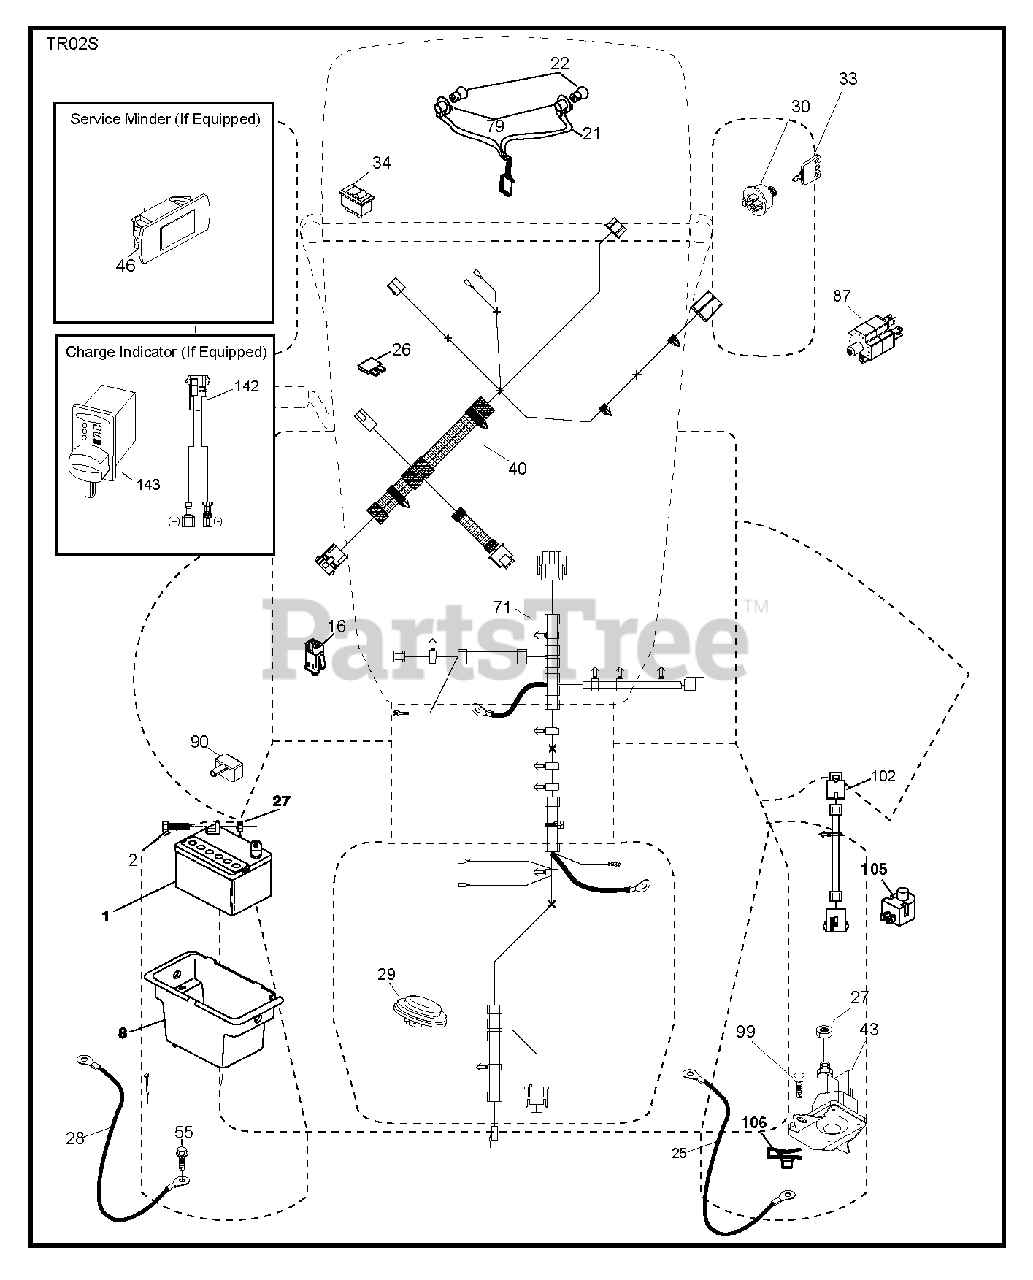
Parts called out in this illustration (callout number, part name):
1	Battery, Dry 30 Amp
2	BOLT.HEX.1/4.X.3/4.DICHROMATE
8	BOX.BATTERY.MNT.REAR.L
16	SWITCH INTERLOOK PUSH-IN
21	HARNESS.LIGHT W/4152J BULBS
25	CABLE.BATT.RED.8GA.17
26	FUSE 20AMP
27	NUT
28	CABLE.GROUND.REAR.BATTERY.8G
29	SWITCH.SEAT.DELTA.OPC.
30	SWITCH.IGN.DELTA.W.LGH.ROS
33	KEY.CHAIN.BLISTER.PACK.GEN.INT
40	HARNESS.DASH.RRBATT.CC.CHG
43	SOLENOID.STARTER.BRASS.PLUNGER
55	SCREW 5/16"
71	HARNESS.CHASSIS.RRBATT.RDYSTRT
79	BULB HOLDER ASM.
87	SWITCH.INTRLCK.CLUTCH.
90	COVER.TERMINAL.BATTERY
99	SCREW HEXWSHR 1/4-20X3/4
102	HARNESS.PIGTAIL.VARIATOR.SD
105	REVERSE SWITCH
106	1/4-20 U NUT
142	CHARGE.PORT.PIGTAIL HARNESS
143	CHARGE.PORT
